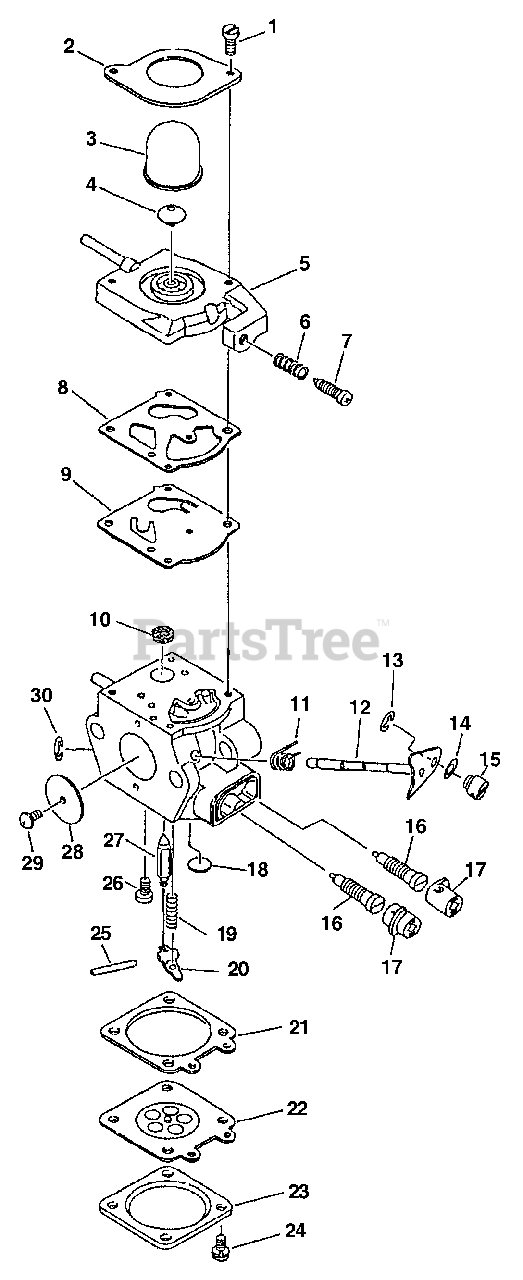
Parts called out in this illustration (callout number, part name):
2	RETAINER, PURGE BULB
3	BULB, PURGE
4	VALVE, CHECK
5	COVER, FUEL PUMP
6	SPRING, IDLE ADJUST
7	SCREW, IDLE ADJUST
10	STRAINER
11	SPRING, THROTTLE RETURN
12	SHAFT, THROTTLE
16	NEEDLE - MIXTURE
17	CAP, LIMITER
18	PLUG, WELCH
19	SPRING, METERING LEVER
20	LEVER, METERING
21	GASKET, METERING
22	DIAPHRAGM, METERING
23	COVER, METERING DIAPHRAGM
24	SCREW
25	PIN, METERING LEVER
26	SCREW, METERING LEVER PIN
27	VALVE, INLET NEEDLE
28	VALVE, THROTTLE
31	DIAPHRAGM/GASKET KIT
32	REPAIR KIT, CARBURETOR
